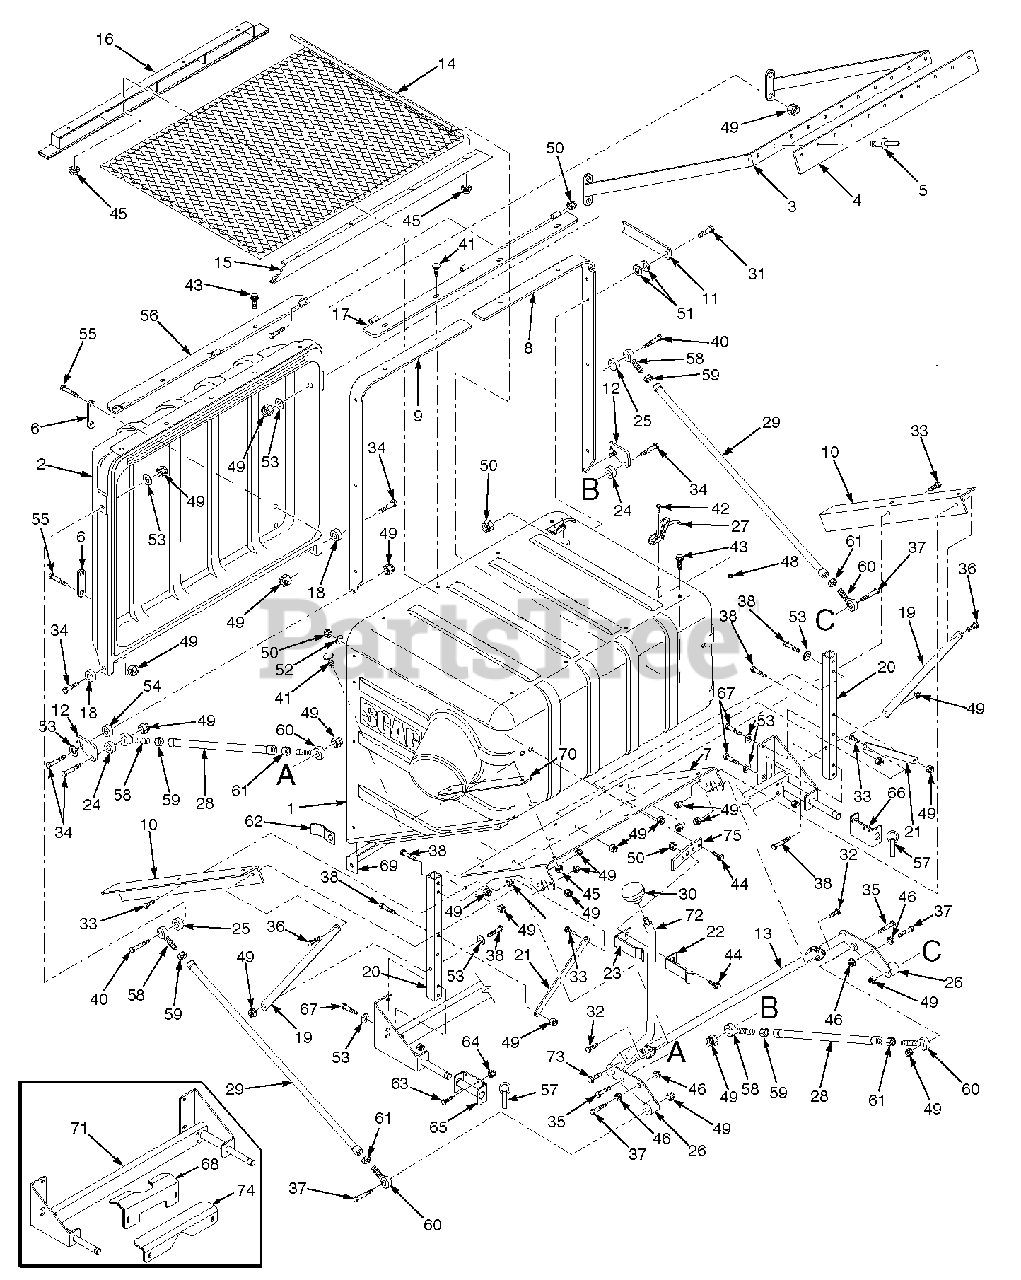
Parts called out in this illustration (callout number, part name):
1	Hopper, GC-STT-CS
2	Door, GC-CS
3	Sweeper Weldment, GC-CS
4	Pad, Rubber
5	Pop Rivet, 3/16 x .652
6	Plate, Stiffener
7	Support Frame, Hopper
8	Hinge Bracket, LH
9	Hinge Bracket, RH
10	Bracket, Hopper Support
11	Latch, Door Prop
12	Plate, Latch
13	Bellcrank Weldment, Upper
14	Debris Screen Weldment
15	Screen Support Weldment, Rear
16	Screen Support Weldment, Front
17	Hinge Weldment, Hopper
18	Spacer
19	Brace Stiffener, Long
20	Tube, Upright
21	Brace, Engine Mount
22	Latch, Dump Rod Inner
23	Latch, Dump Rod Outer
24	Spacer
25	Spacer
26	Spacer
27	Latch, Hood
28	Linkage Assembly, Lower
29	Linkage Assembly, Upper
31	Bolt, Hex Head 5/16-18 x 1-1/4"
32	Bolt, Hex Head 3/8-16 x 3/4"
33	Bolt, Hex Head 3/8-16 x 1"
34	Bolt, Hex Head 3/8-16 x 1-1/2"
35	Bolt, Hex Head 3/8-16 x 1-3/4"
36	Bolt, Hex Head 3/8-16 x 1-1/4"
37	Bolt, Hex Head 3/8-16 x 2"
38	Bolt, Hex Head 3/8-16 x 2-1/4"
39	Bolt, Hex Head 5/16-18 x 3-1/2"
40	Bolt, Hex Head 3/8-16 x 3-1/2"
41	Bolt, Carriage 5/16-18 x 1"
42	Screw, #10-32 x 1/2"
43	Cap Screw, 5/16-18 x 3/4" Serr. Flan.
44	Cap Screw, 5/16-18 x 1" Serr. Flan.
45	Nut, 5/16-18 Serrated Flange
46	Nut, 3/8-16 Serrated Flange
47	Nut, 3/8-16 UNC Jam
48	Nut, #10-32 Elastic Stop
49	Nut, 3/8-16 Elastic Stop
50	Nut, 5/16-18 Elastic Stop
51	Washer, Special Wave
52	Washer, 5/16-.375 x .875 x .083 Flat
53	Washer, 3/8-.931 x .938 x .105 Flat
54	Bushing, Hopper Latch GC-CS
55	Bolt, Hex Head 3/8-16 x 3"
56	Hinge Weldment, Door
58	Rod End Male, 3/8-24 LH Thread
59	Nut, 3/8-24 UNF LH Thread
60	Rod End Male, 3/8-24 RH Thread
61	Nut, 3/8-24 UNF RH Thread
62	Alignment Bracket, GC-CS
63	Bolt, Hex Head 3/8-16 x 1"
64	Nut, 3/8-16 Elastic Stop
65	Hitch Bracket Weldment
66	Hitch Bracket Weldment, Floating
67	Bolt, Hex Head 3/8-16 x 3-3/4"
68	Support Bracket, Catcher STT
69	Bracket, Lower Stiffener
70	Retainer Strip, Hopper
71	Frame Weldment
72	Rod, Dump Lever GC-SCZ-CS
73	Bolt, Hex Head 5/16-18 x 1-3/4"
74	Support Bracket, GC (SCZ Only)
75	Mounting Bracket, Dump Handle Latch
